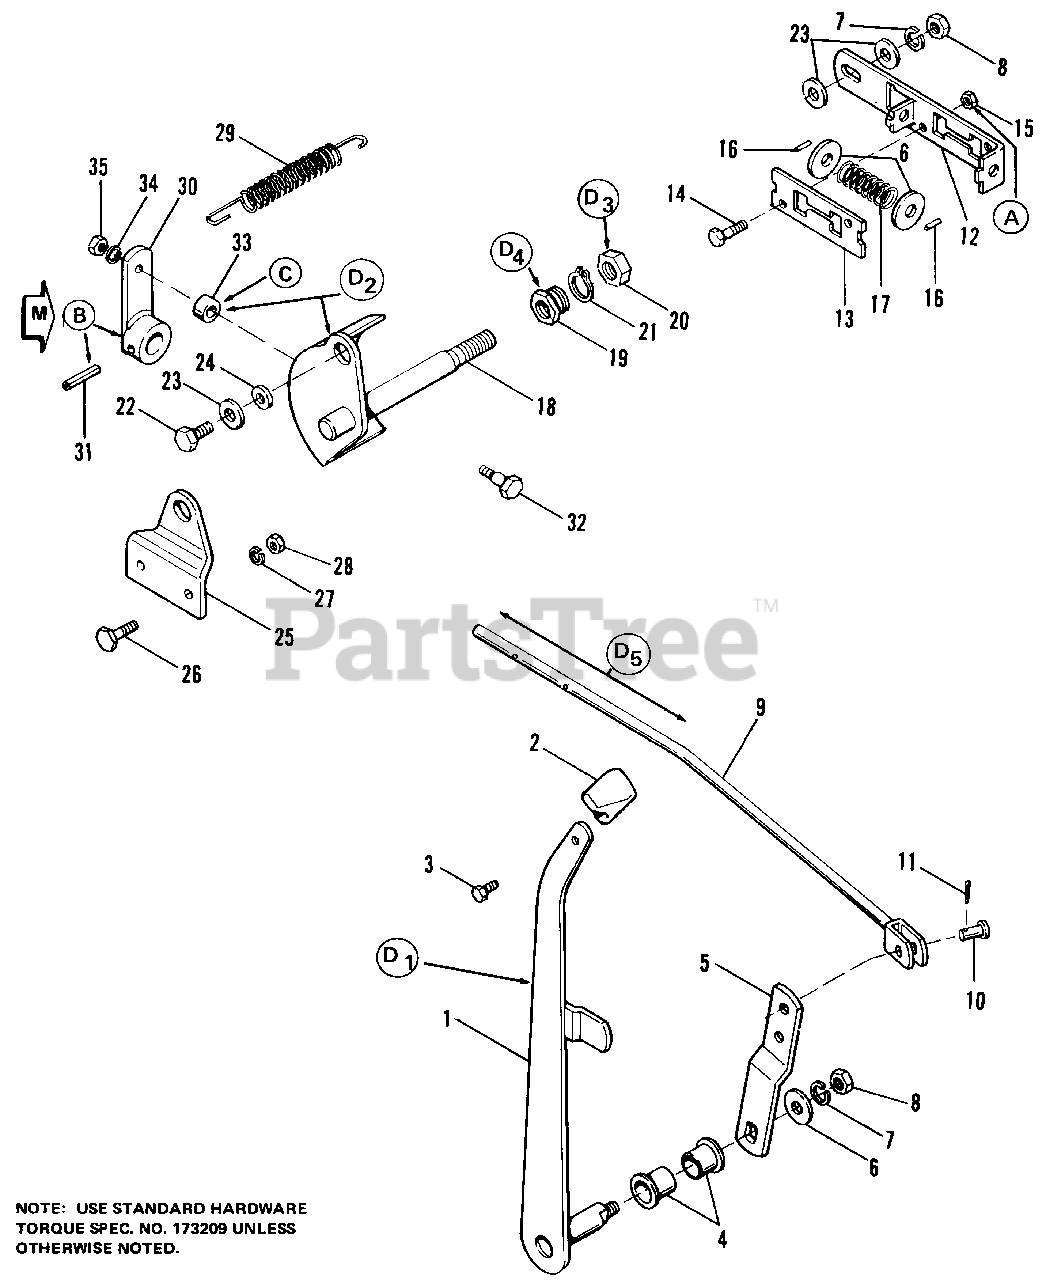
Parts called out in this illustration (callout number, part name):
1	LEVER ASSY, Control
3	SCREW, Thd. Form., 1/4-20 x 3/4
6	WASHER, 3/8
7	LOCKWASHER, 3/8
8	NUT, Hex, Full, 3/8-16
9	ROD ASSY, Control
11	PIN, Cotter, 3/32 x3/4
12	GUIDE, Control Rod
13	PLATE, Guide
14	CAPSCREW, Hex Hd., 1/4-20 x 1-1/4
15	LOCKNUT, Hex, 1/4-20
19	NUT, Adjusting
20	NUT, Hex, Jam, 1/2-13
21	RING, Retaining
22	CAPSCREW, Hex Hd., 3/8-16 x 1
23	WASHER, 5/16
25	BRACKET, Pivot
26	SCREW, Special
27	LOCKWASHER, 5/16
28	NUT, Hex, Full, 5/16-18
30	LINKS ASSY, Control
31	PIN, Roll, 1/4x 1-1/4
32	BOLT, Shoulder
33	ROLLER, Cam
34	LOCKWASHER, 1/4
35	NUT, Hex, Full, 1/4-20
